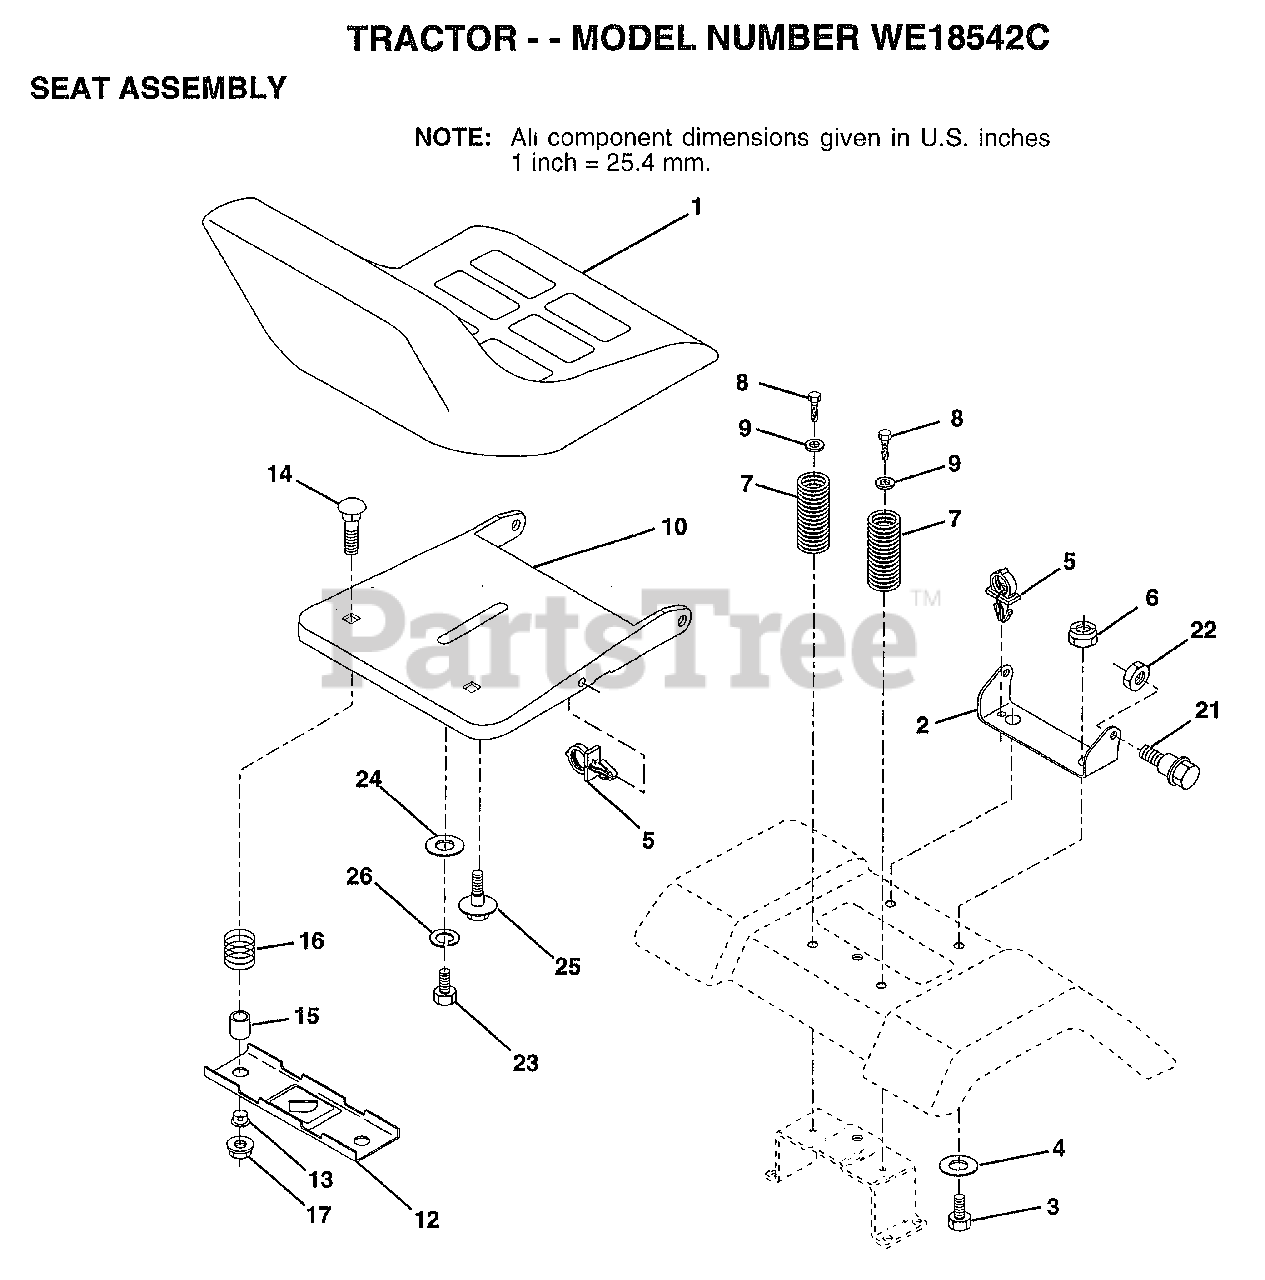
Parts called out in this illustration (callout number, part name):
2	BRACKET PVT SEAT
3	BOLT
4	WASHER PM
5	CLIP.PUSH-IN.HING
6	NUT
7	SPRING COMPRESSIO
8	SCREW GTV
9	WASHER
10	PAN-SEAT
12	BRKT SWITCH
13	BUSHING
14	BOLT-RD HD SQ NK
15	SPLIT SPACER
21	"BOLT,SHOULDER"
22	NUT
23	BOLT
24	WASHER
25	"BOLT,SHOULDER"
26	LOCKWASHER
